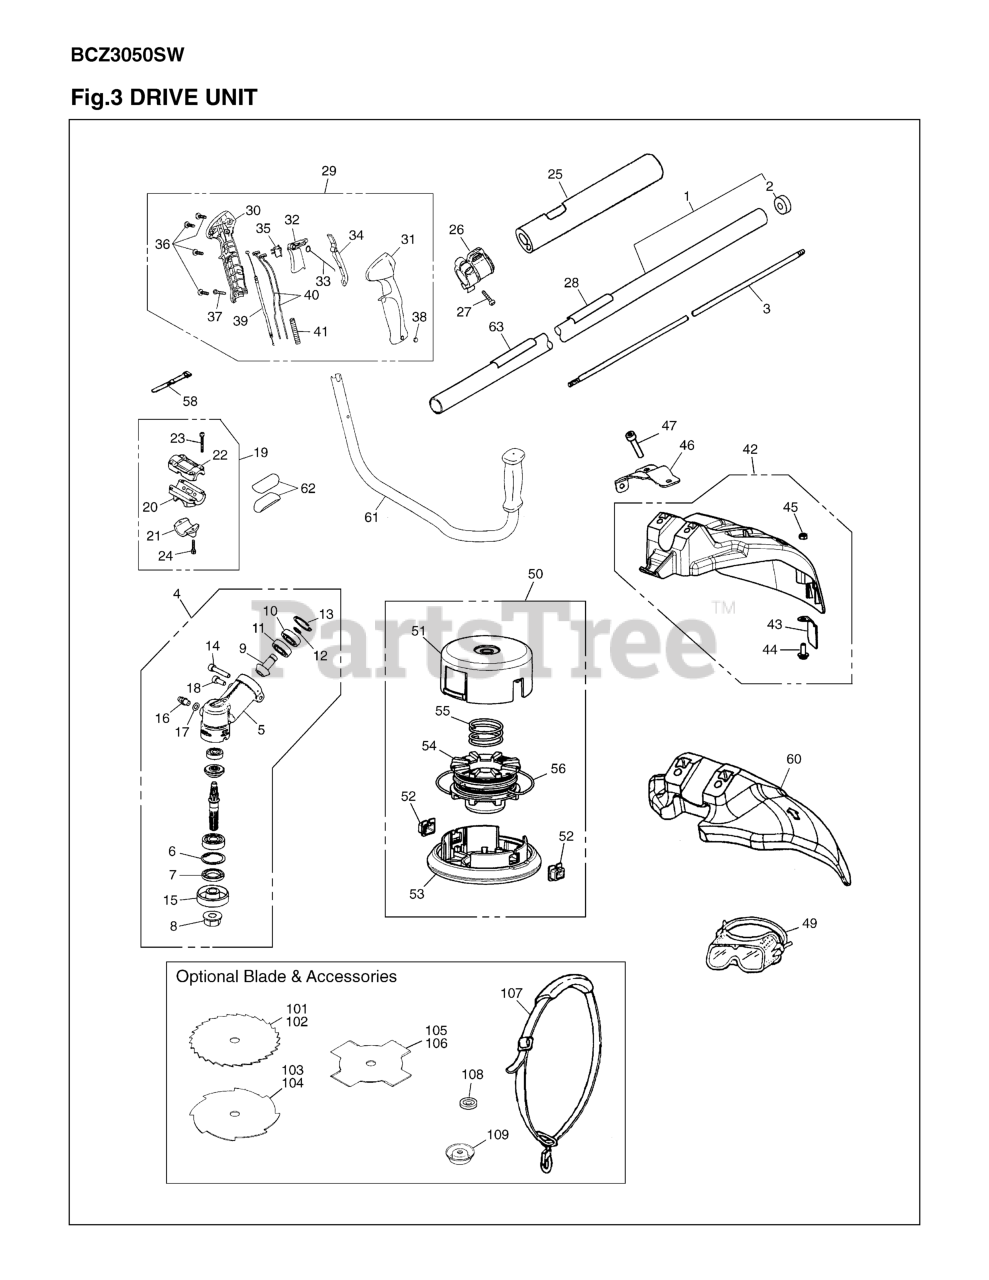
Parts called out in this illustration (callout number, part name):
1	PIPE COMP.
2	SEAL
3	SHAFT
4	GEARCASE ASSY.
5	GEARCASE
6	SNAP RING
7	SEAL
8	NUT
9	PINION
10	BEARING
11	BEARING
12	SNAP RING
13	SNAP RING
14	BOLT, TORX
15	HOLDER (A)
16	FITTING, GREASE
17	WASHER, FITTING
18	BOLT
19	BRACKET ASSY
20	BRACKET
22	BRACKET-UP
23	BOLT TORX
25	PROTECTOR
26	HANGER ASSY
27	SCREW
28	NAME PLATE
29	GRIP ASSY
32	LEVER
33	SPRING
34	LEVER-S
35	SWITCH
36	SCREW
37	SCREW TORX
38	NUT
39	CABLE COMP
40	CORD COMP
41	TUBE
42	GUARD COMP.
43	BLADE
44	SCREW TORX
45	NUT
46	BRACKET
47	BOLT, TORX
49	GOGGLE
50	TAP HEAD COMP.
51	CASE
52	EYELET
53	COVER
54	CORD HOLDER
55	SPRING
58	BAND
60	GUARD
61	HANDLE COMP.
62	PLATE
63	LABEL, CAUTION
101	BLADE, 9
102	BLADE, 9
103	BLADE, 8
104	BLADE, 9
105	BLADE, 8
106	BLADE, 9
107	STRAP ASSY
108	HOLDER (B)
109	COVER
